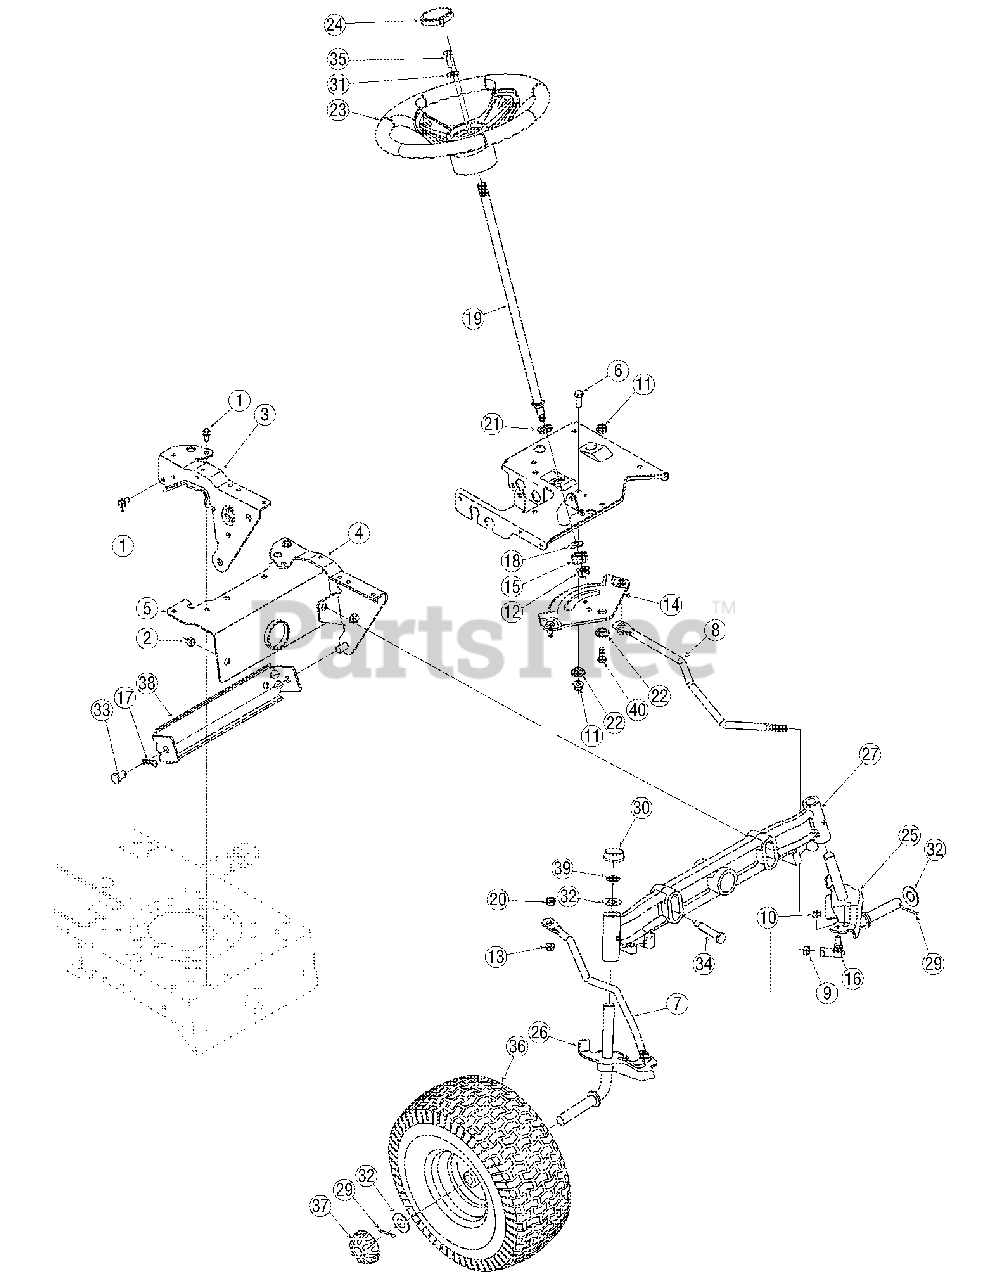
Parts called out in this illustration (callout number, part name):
1	Self-tapping Screw, 5/16-18 x.75
2	Nut, Flange Lock, 3/8-16
6	Hex Cap Screw, 3/8-16 x 1
7	RH Drag Link
8	LH Drag Link
9	Jam Nut, 7/16-20
10	Hex Nut, 3/8-24
11	Flange Lock Nut, 3/8-16
12	Flange Lock Nut, 7/16-20
13	Flange Lock Nut, 5/16-18
14	Steering Gear, 11/90 Ratio
15	Steering Pinion Gear
16	Ball Joint, 7/16-20
17	Cotter Pin, Internal
18	Flat Washer,.51 x 1.12 x.06
19	Steering Shaft,.625 OD x 24.4
20	Plastic Bushing,.38 ID
21	Hex Flange Bearing, 5/8
22	Shoulder Spacer,.38 x 1.00 x.31
23	Steering Wheel, Soft Grip, Three Spoke
24	Steering Wheel Cap
25	LH Axle Assembly,.75 Diameter
26	RH Axle Assembly,.75 Diameter
27	Cast Iron Pivot Bar
29	Cotter Pin
31	Flat Washer,.406 x.875 x.105
32	Flat Washer,.78 x 1.59 x.06
33	Pin, Clevis,.50 Dia. x.78 Lg.
34	Shoulder Screw,.5 x 2.2, 3/8-16
35	Hex Bolt, 5/16-18 X 1
36	Flange Bearing
36	Flange Bearing w/ Grease Fitting
37	Hub Cap
39	Nut, Push, 3/4 Dia.
40	Hex Bolt 3/8-16 x 1.0 Special
